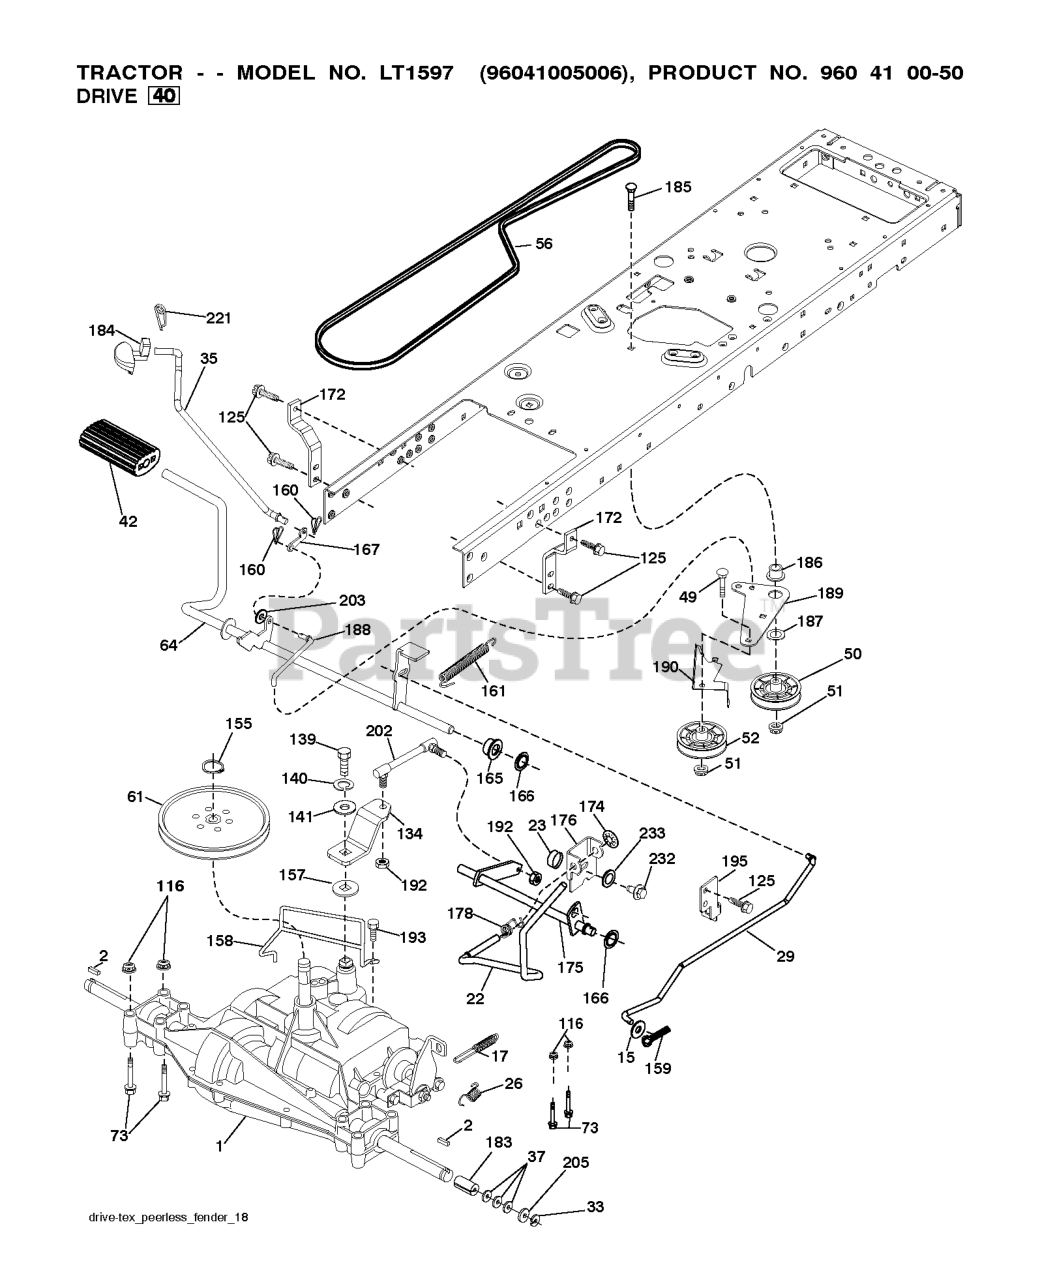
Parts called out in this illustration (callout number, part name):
2	SQUARE KEY
15	WASHER
17	SPRING.BRAKE.PEERLESS.TEX
22	ROD.SHIFT.FENDER.TLT.2006
23	KNOB.DUCKHEAD.1/2
26	SPRING.BRAKE.RTN.GR.DR
29	ROD.BRAKE.PEERLESS
35	ROD.CNTRL.PARK.PREDATOR.LT.TEX
42	PEDAL COVER T
50	IDLER.FLAT.910.OFFSET
51	NUT LOCK FLG 3/8-16 UNC
52	IDLER.V-GROOVE.910.OFFSET
56	V-BELT.TRACTOR.DRIVE.P
61	PULLEY TRANS
64	SHAFT.ASM.PEDAL.BRAKE.
73	BOLT HEX 5/16-18 GR 5
116	NUT LOCK HEX FLANGE 5/16-18
125	SCREW
139	BOLT 1/4-28X3/4
140	LOCKWASHER
155	RETAINING RING LT
157	WASH-SHFT PLT LT
158	KEEPER.PMS.18/20.D4365
159	COTTER PIN
160	RETAINER CLIP
161	SPRING, RETURN LT
165	BUSHING.SHAFT.BRAKE.HAND
166	NUT.PUSH.625
167	LATCH.BRAKE.SPRING
172	STRAP.TRQ.LH.GEAR.DRIV
174	NUT.PUSH.500.2006
175	SHAFT ASM SHIFT
176	ARM.CLEVIS.ROD.SHIFT
178	SPRING.SHIFT.GT2006
183	SPACER AXLE
184	HANDLE PARKING BRAKE
186	SPACER.RETAINER
187	WASHER 12/32X2X10GA
188	RP.LINK.CLUTCH.GROUND.DRIVE
189	BELLCRANK.GROUND.DRIVE.TEX.
190	KEEPER.BELLCRANK.DRIVE
192	NUT LOCK CENTER 1/4 -28 FNTHD
193	SCREW 5/16"
195	BRKT.ROD.BRAKE.PEERLES
202	LINK.SHIFT.PMST.18" (SPG1286)
203	WASHER
221	RETAINER.SPRING.CLIP.H
232	BOLT FIN HEX 7/16-14 X 1
233	WASHER SERRATED
